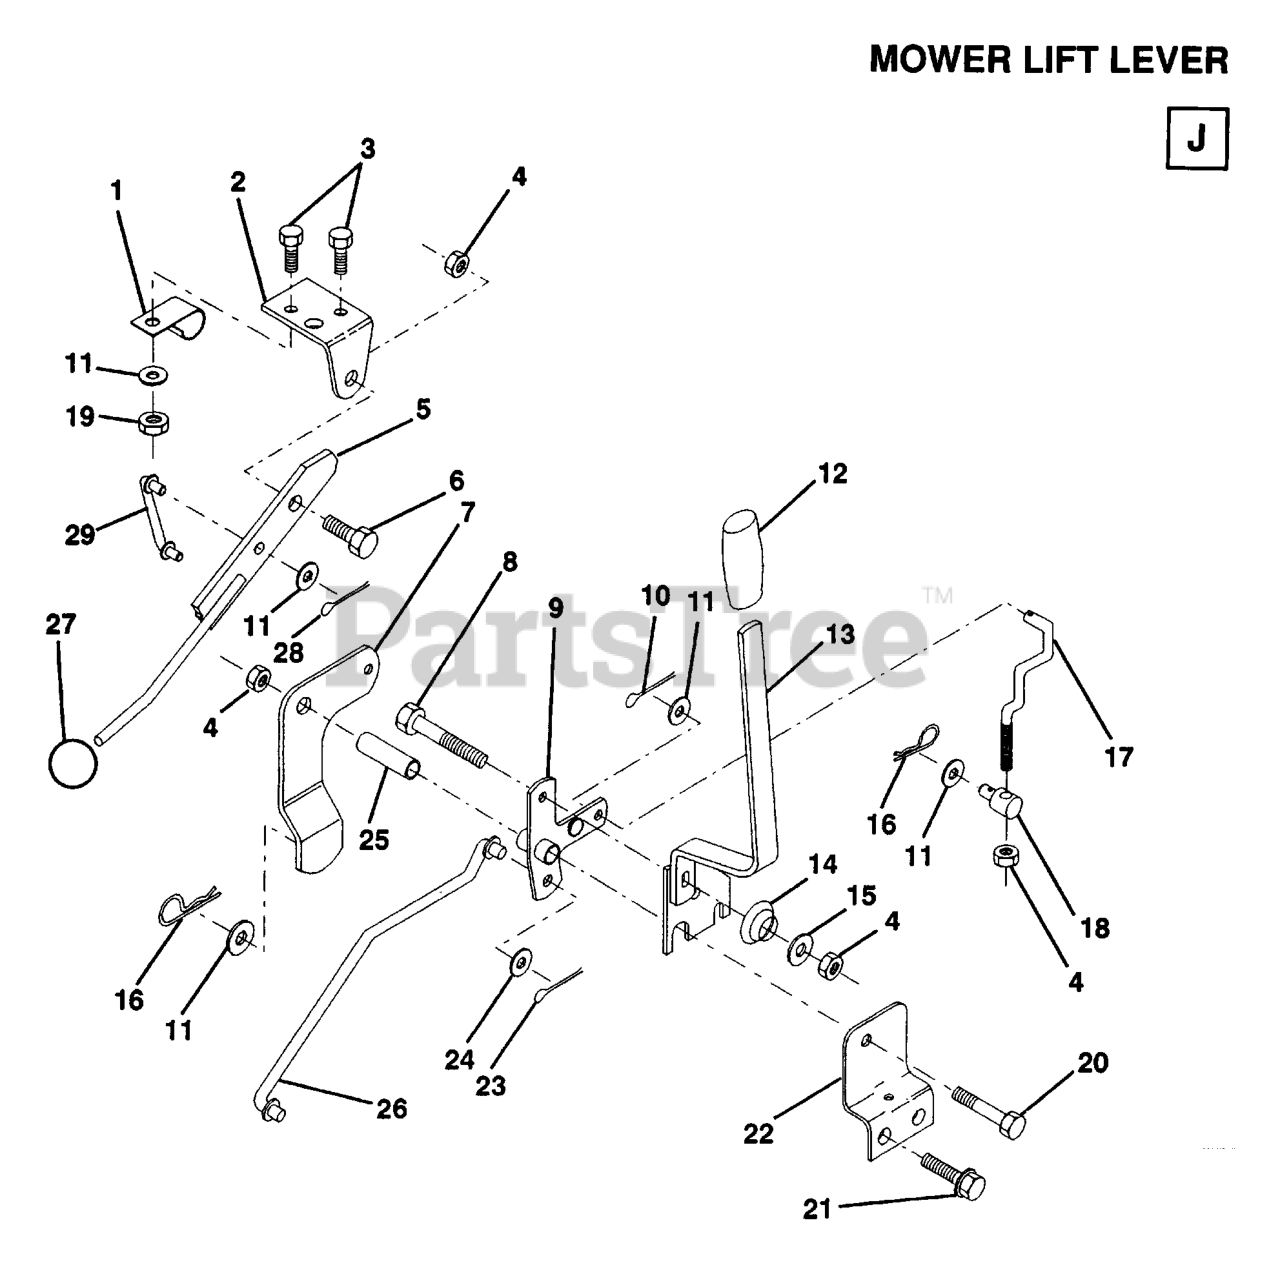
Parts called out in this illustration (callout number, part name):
1	CLIP,INSULATOR
2	BRKT CLUTCH
3	BOLT
5	CLUTCH LEVER ASSY
6	BOLT, SHOULDER LT
7	CLUTCH ARM ASS'Y
9	BELLCRANK,LIFT
10	PIN COTTER
11	WASHER
12	GRIP HANDLE
12	HANDLE GRIP
13	HDLE, LIFT T
14	SPRING COMPRESSIO
15	WASHER
16	COTTER PIN
17	LINK LIFT FRT
18	TRUNION
19	NUT.CROWNLOCK.1/4
21	Screw 5/16-18 x 1/2 Hex, Self Tapping 5/16-18 x 1/2
22	BRKT,MOWER HGT
23	PIN COTTER
24	WASHER
25	TUBE SPACER
26	ROD,MOWER LIFT
27	KNOB
27	KNOB T (3/8 HOLE)
28	COTTER PIN
29	LINK,MOWER LIFT
